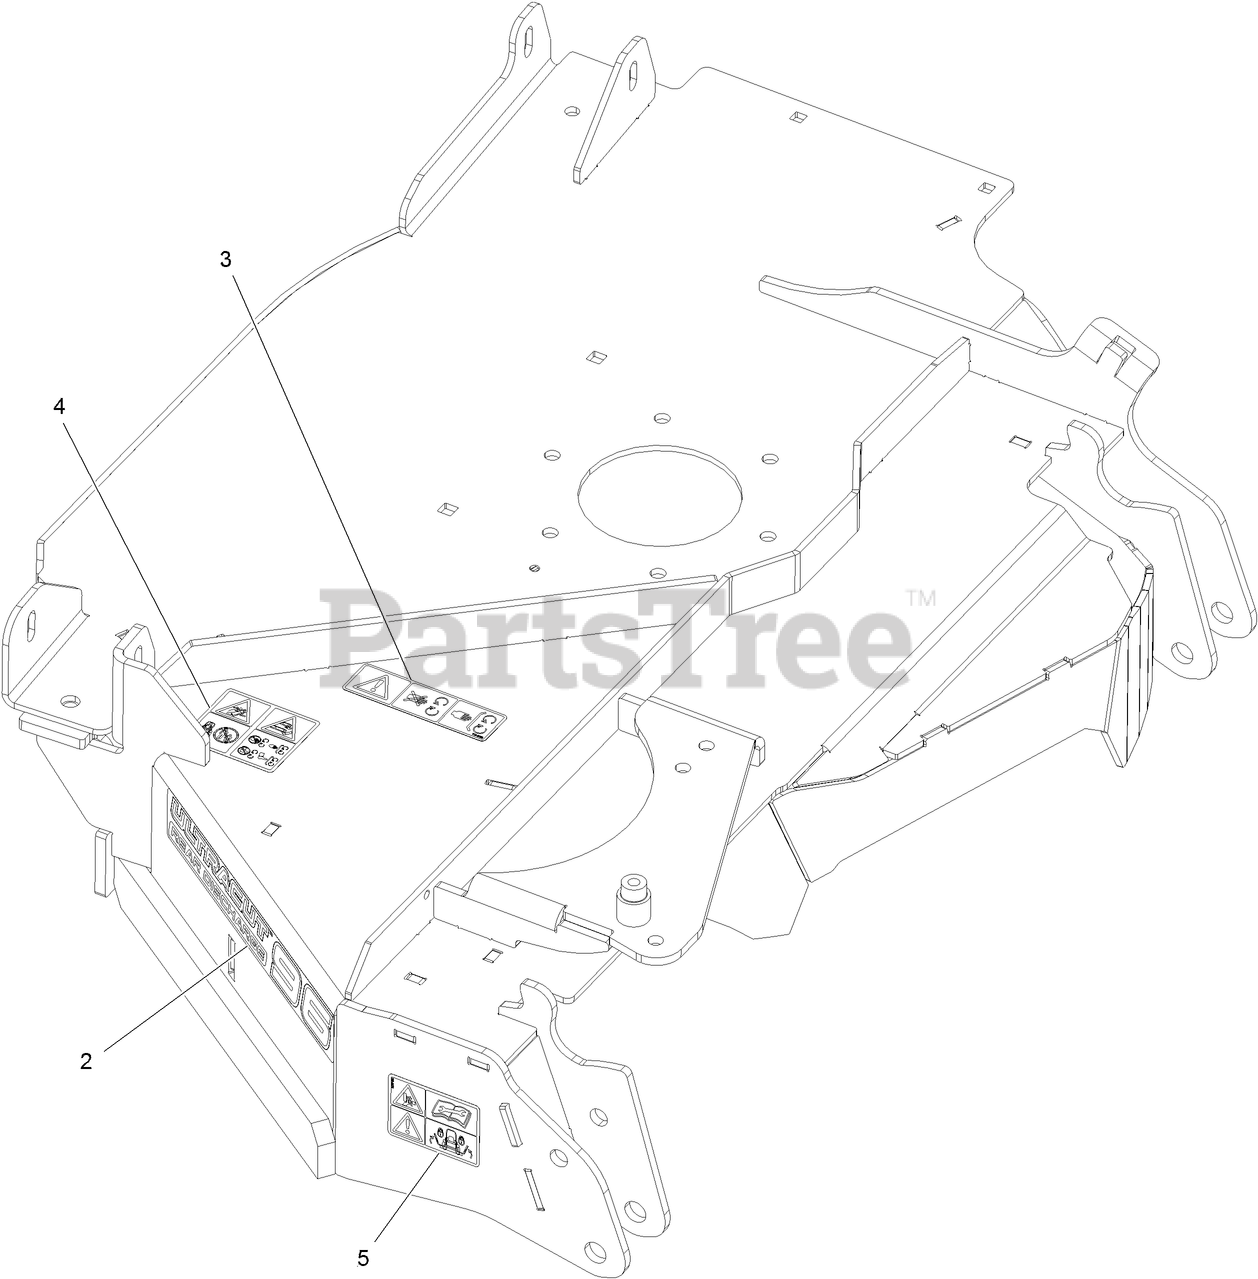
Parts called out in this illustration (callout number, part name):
2	DECAL-ULTRACUT 96-RD
3	DECAL-COVER, MISSING
4	DECAL-DANGER, THROWN OBJECT
5	DECAL-WARNING, PINCH POIN
